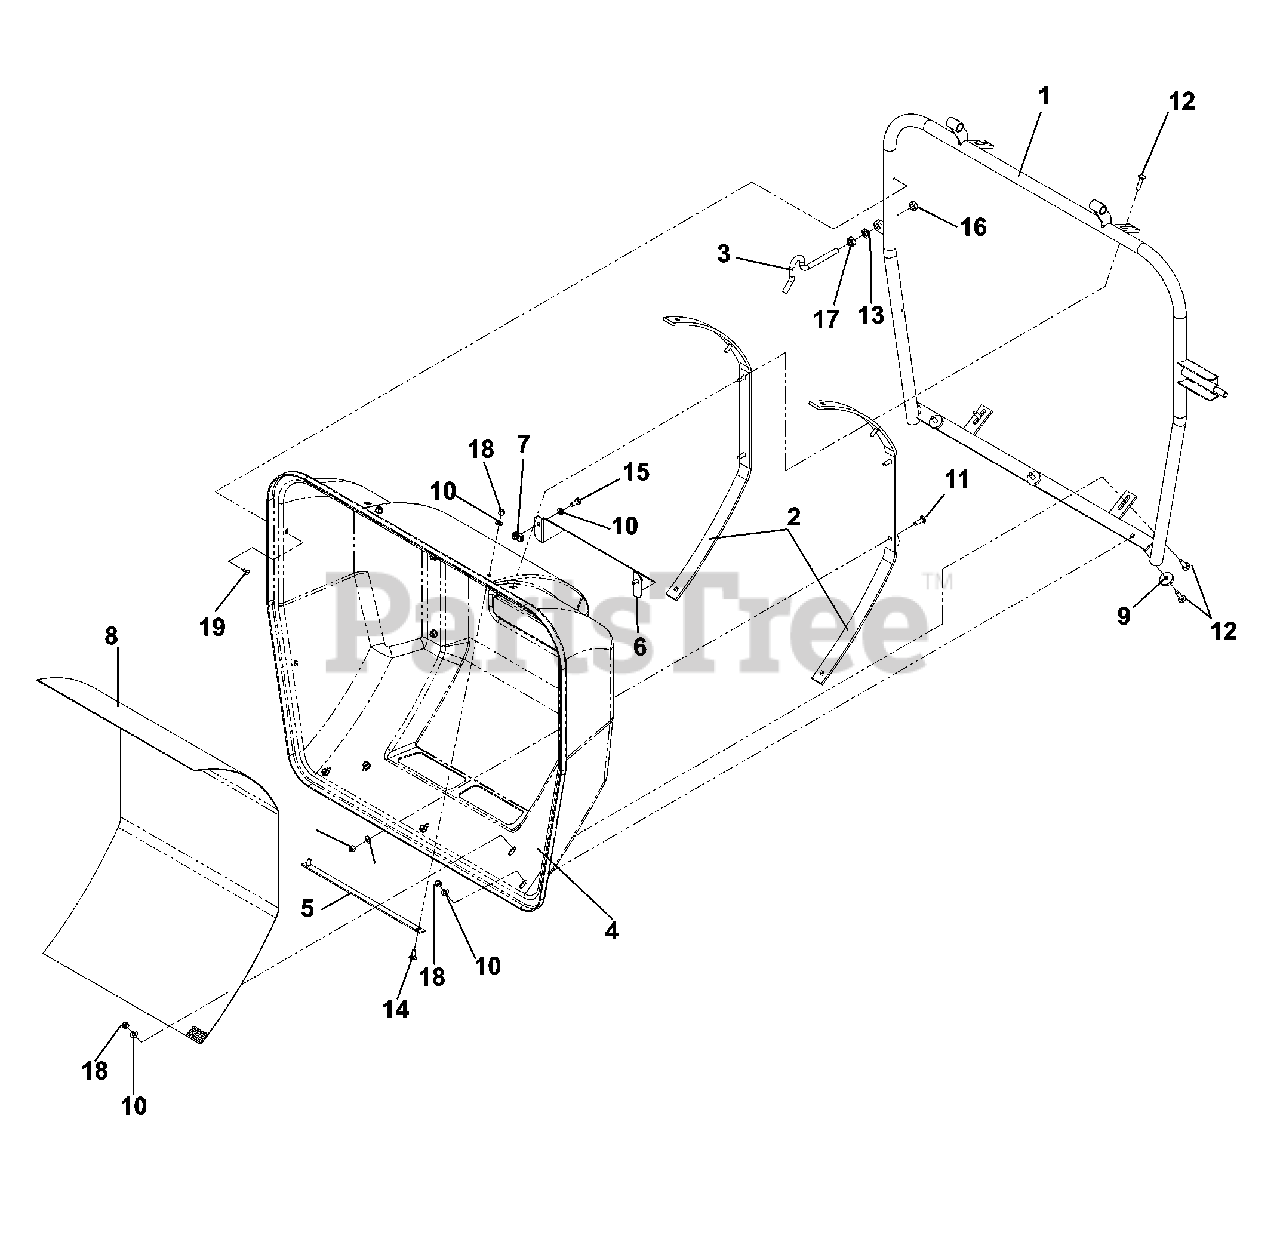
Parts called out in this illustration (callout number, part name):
1	DRIVE PULLEY
3	HOOK LATCH
4	CLAM SHELL (BACK)
6	CLAMSHELL VENT
7	CLIP NUT 5/16-18
8	VENT SCREEN
9	WASHER NYLON
10	FLAT WASHER 5/16 SAE
11	RHSSNB 5/16C X 1.0
12	BOLT, CARRIAGE 5/16X1-1/4
13	WASHER 1/2" SPLIT LOCK
14	BOLT 5/16C X 3/4" CARRIAGE
15	SCREW 5/16C X 1 HEX CAP
16	NUT, 1/2-13 THIN PROF NYL
17	NUT 1/2 HEX JAM
18	NUT 5/16 NYLOC
19	LARGE DOME RIVET
